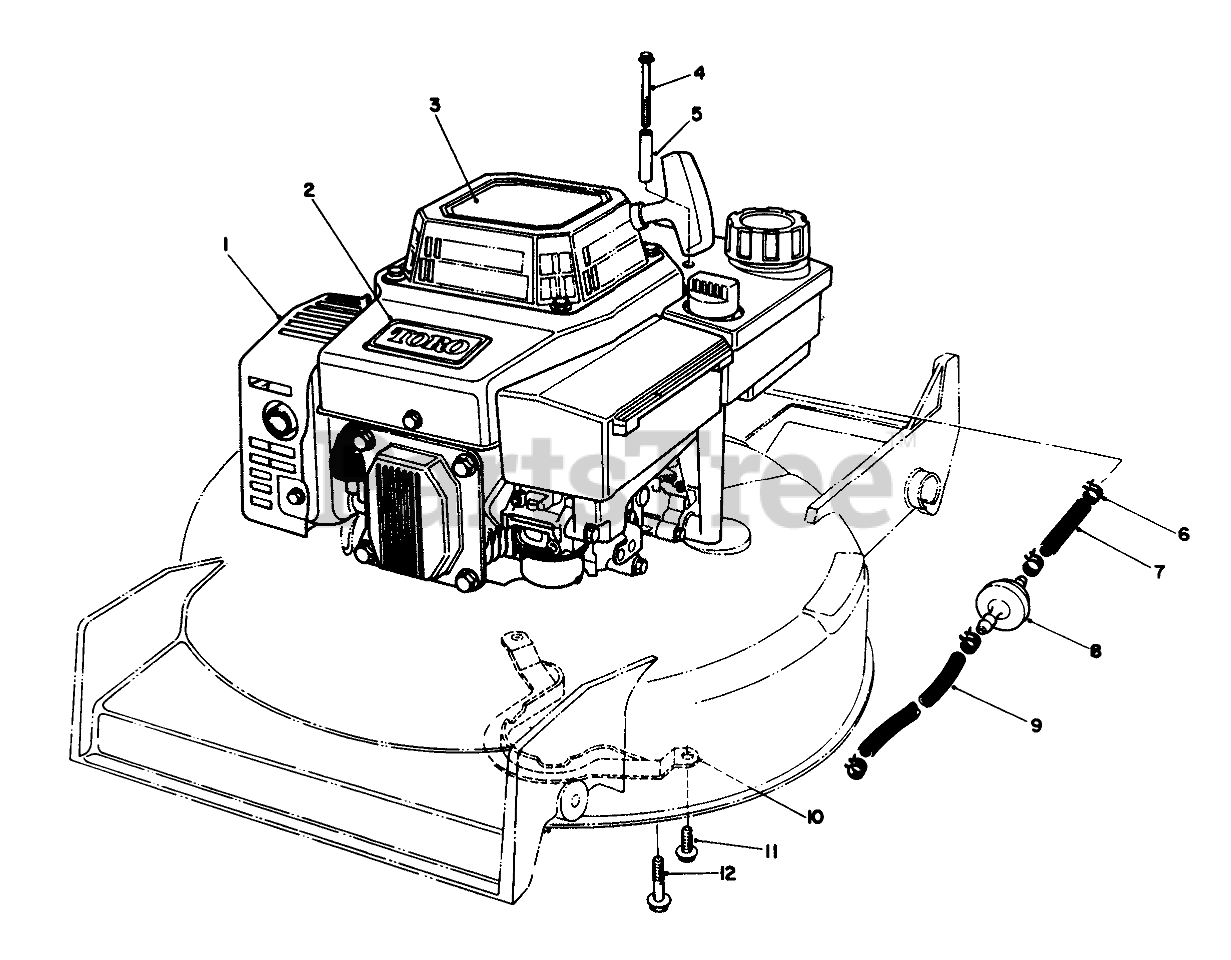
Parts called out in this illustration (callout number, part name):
1	ENGINE ASSY BBC OHV SU
2	TORO LOGO PLT
3	DECAL - OHV RECOIL
4	THRD FORMING SCREW
5	TUBULAR SPACER
6	CLAMP-FUEL LINE
7	LINE-GAS
8	FILTER-FUEL
9	HOSE-FUEL
10	BBC BELT GUIDE
11	SCREW-HWHTF
12	SCREW-HWHTF
